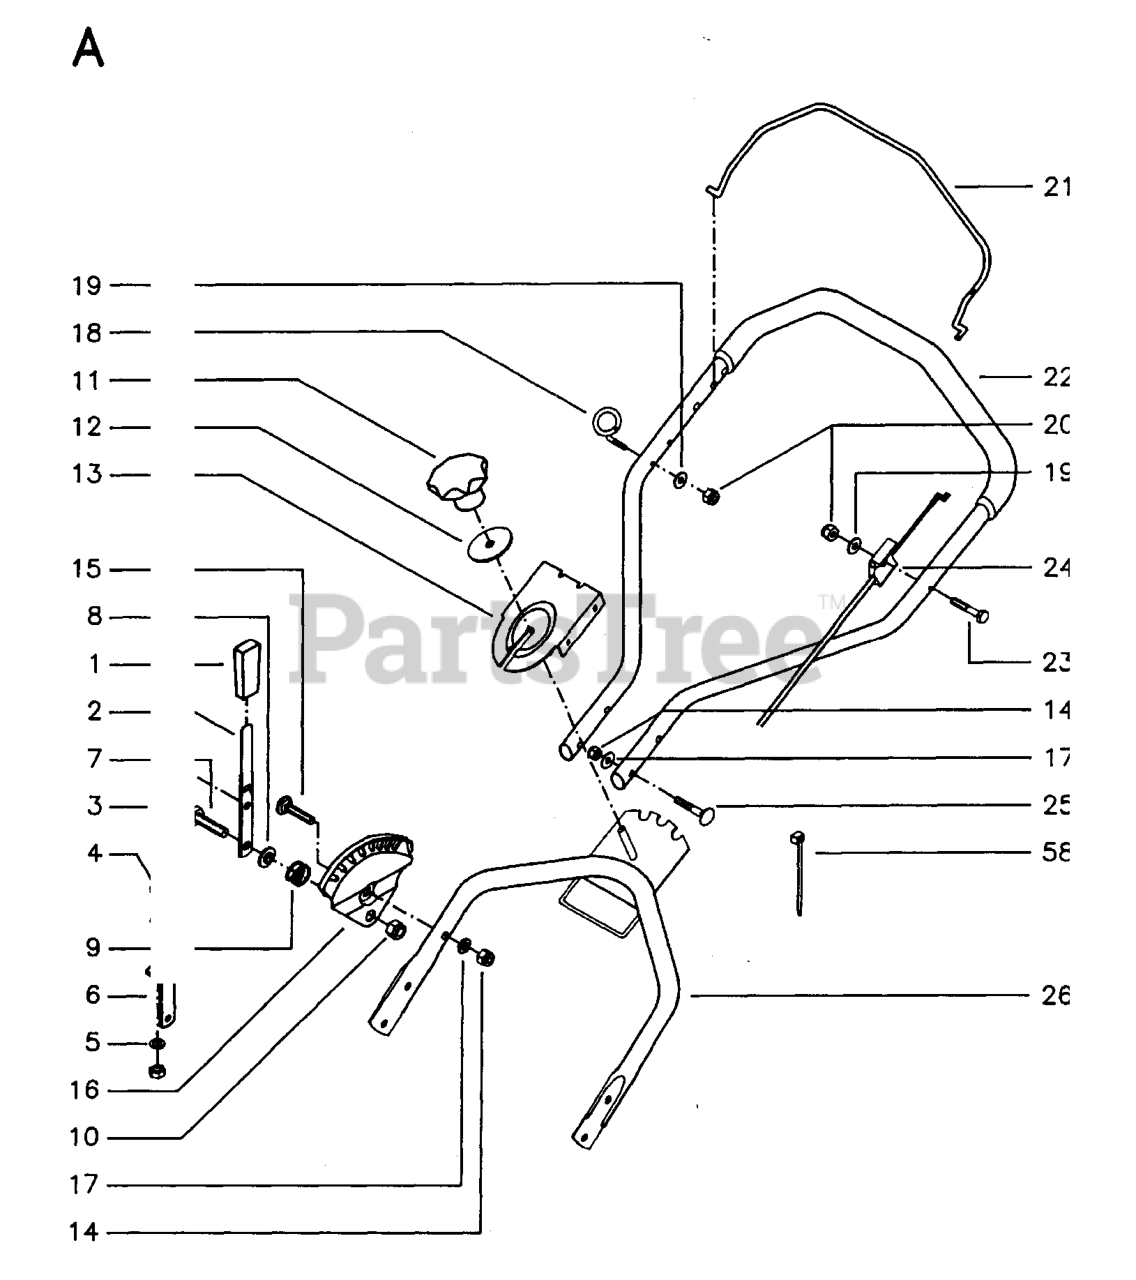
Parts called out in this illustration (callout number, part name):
2	CLUTCH ARM
4	NUT
5	STAR WASHER
9	PRESSURE SPRING
14	LOCKNUT M8
16	INDEXPLATE
17	WASHER - 15X7.3X1.6
20	LOCKNUT M6
23	BOLT FLANGE
